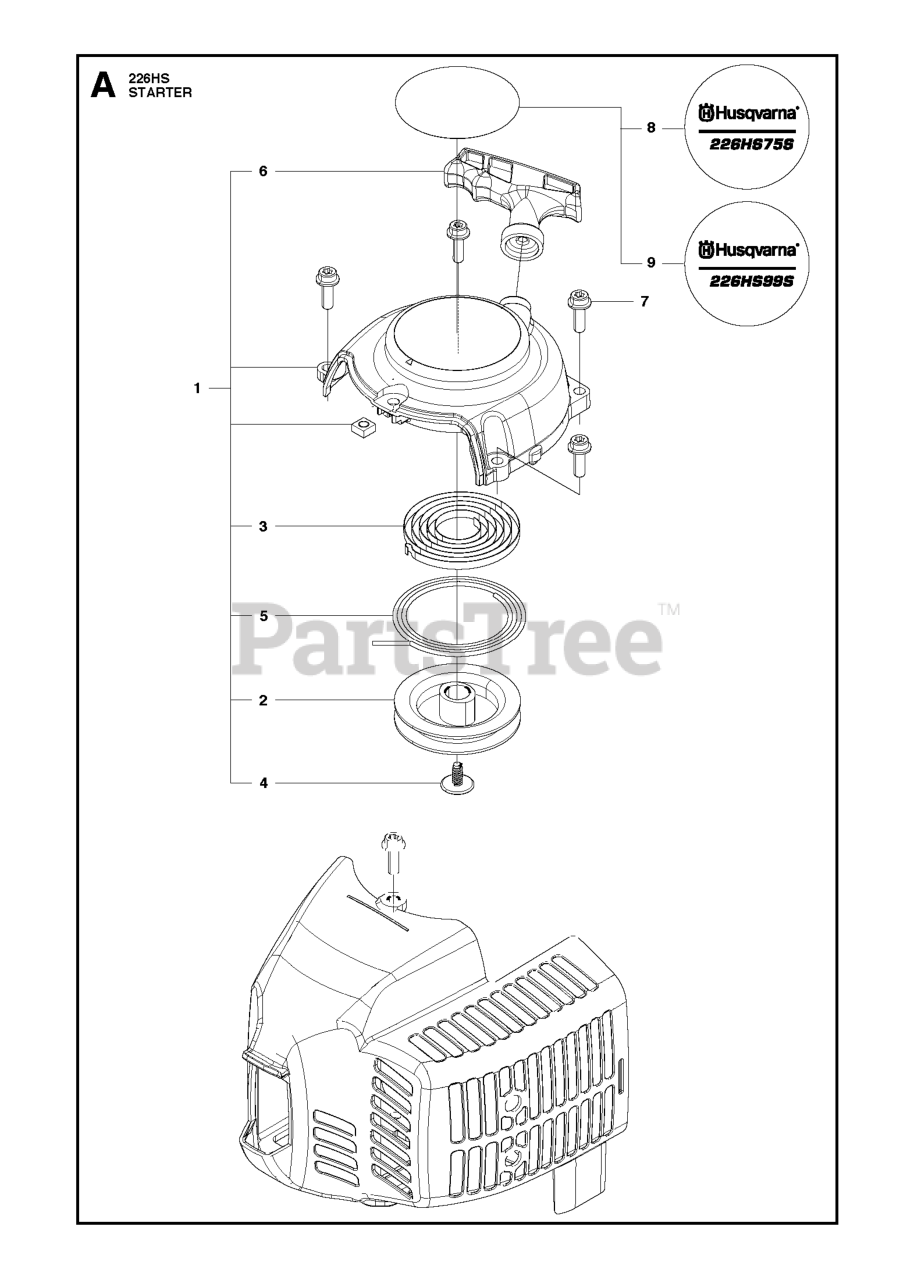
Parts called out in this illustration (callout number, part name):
1	RECOIL ASSY
4	SCREW
8	LABEL,RECOIL
